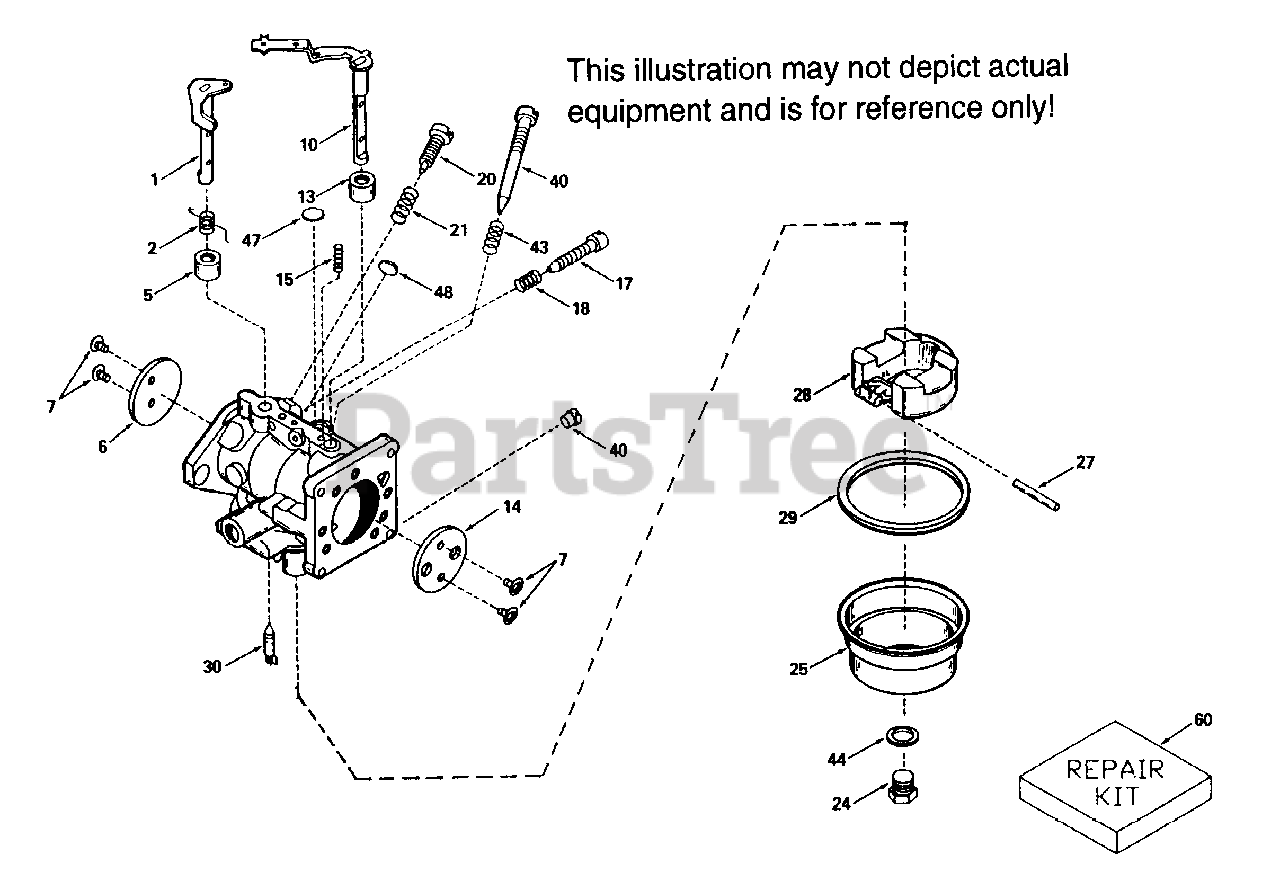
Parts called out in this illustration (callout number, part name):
1	Throttle Shaft & Lever Ass'y.
2	Throttle Return Spring
5	* Dust Seal (Throttle)
6	Throttle Shutter
7	Throttle & Choke Shutter Screw
10	Choke Shaft & Lever Ass'y.
13	* Dust Seal (Choke)
14	Choke Shutter
15	Choke Positioning Spring
17	Idle Speed Screw
18	Tension Spring
20	* Idle Mixture Screw
21	Idle Tension Spring
25	Float Bowl
27	* Float Shaft
29	* Float Bowl "O" Ring
30	* Inlet Needle
40	Bowl Nut
40A	High Speed Jet
44	* Bowl Nut Washer
47	* Welch Plug
48	* Welch Plug
60	Repair Kit (Incl. items marked PK in notes) Incl. (1) each of part #'s2711 2, 632039, 632443, 632444,632446, 632 447, 632448
